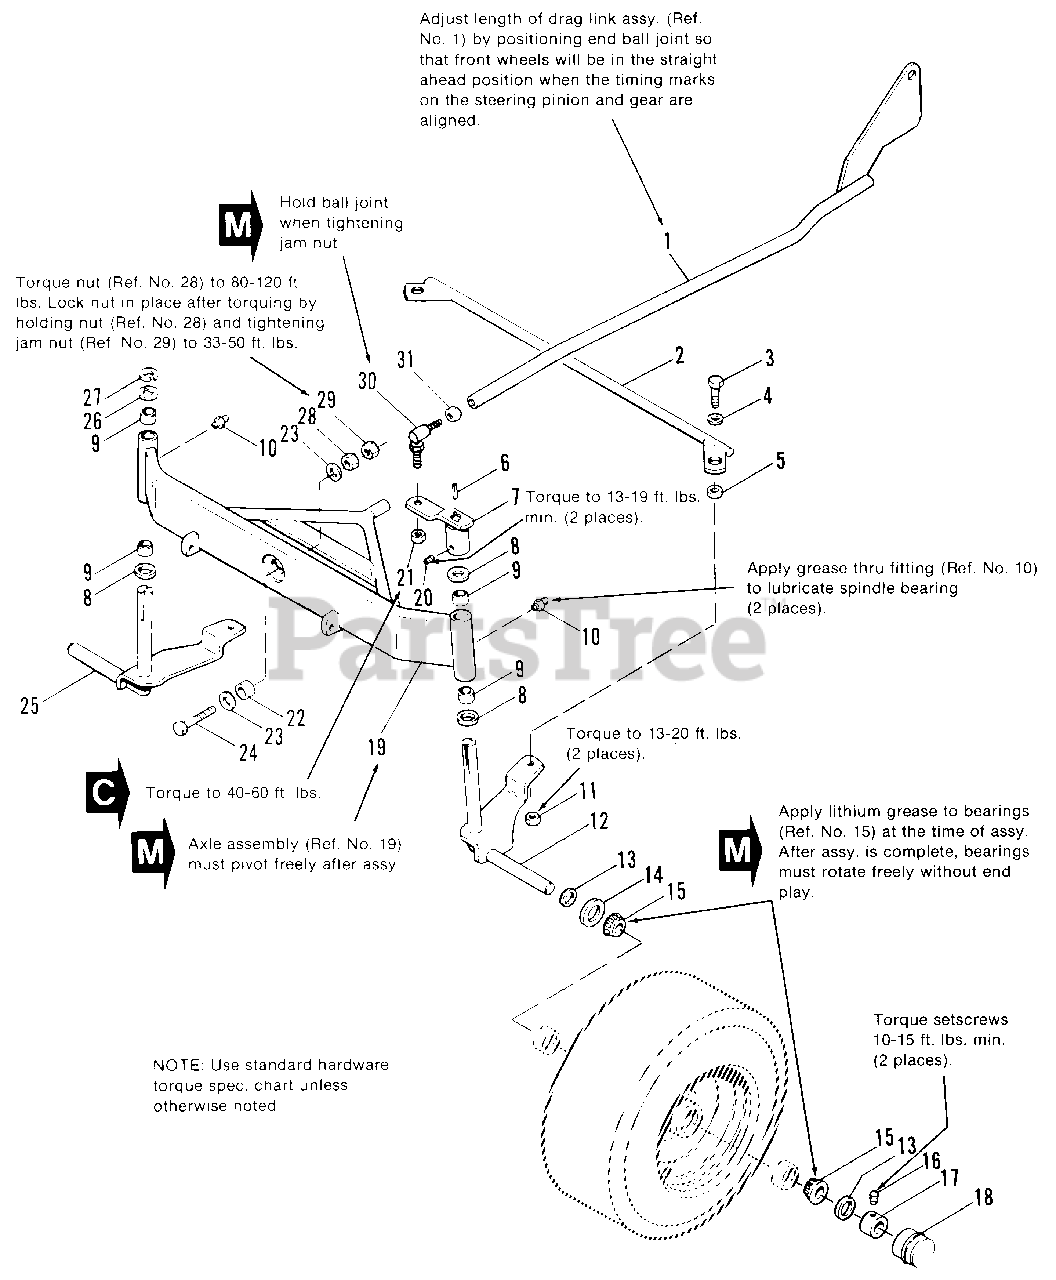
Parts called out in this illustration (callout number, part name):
1	LINK ASSY., Drag
2	ROD ASSY., Tie
3	CAPSCREW, Hex Hd., 3/8-16 x 1
4	WASHER, Plain, 3/8
6	KEY, Square
7	ARM ASSY., Steering
8	WASHER
10	FITTING, Grease
11	LOCKNUT, Hex, 3/8-16
12	SPINDLE ASSY., LH
15	CONE, Bearing
16	SETSCREW, 5/16-18 x 5/16
17	COLLAR, Set
18	CAP, Hub
19	AXLE ASSY., Front (Incl. Ref. No. 9)
20	SETSCREW, 5/16-18 x 1/2
21	LOCKNUT, Hex, 1/2-20
23	WASHER, Plain, 1/2
24	CAPSCREW, Hex Hd., 1/2-13 x 2-1/4
25	SPINDLE ASSY., RH
27	RING, Retaining
28	LOCKNUT, Hex, 1/2-13
29	LOCKNUT, Hex, Jam, 1/2-13
30	BALL, Joint
31	LOCKNUT, Hex, Jam, 1/2-20
